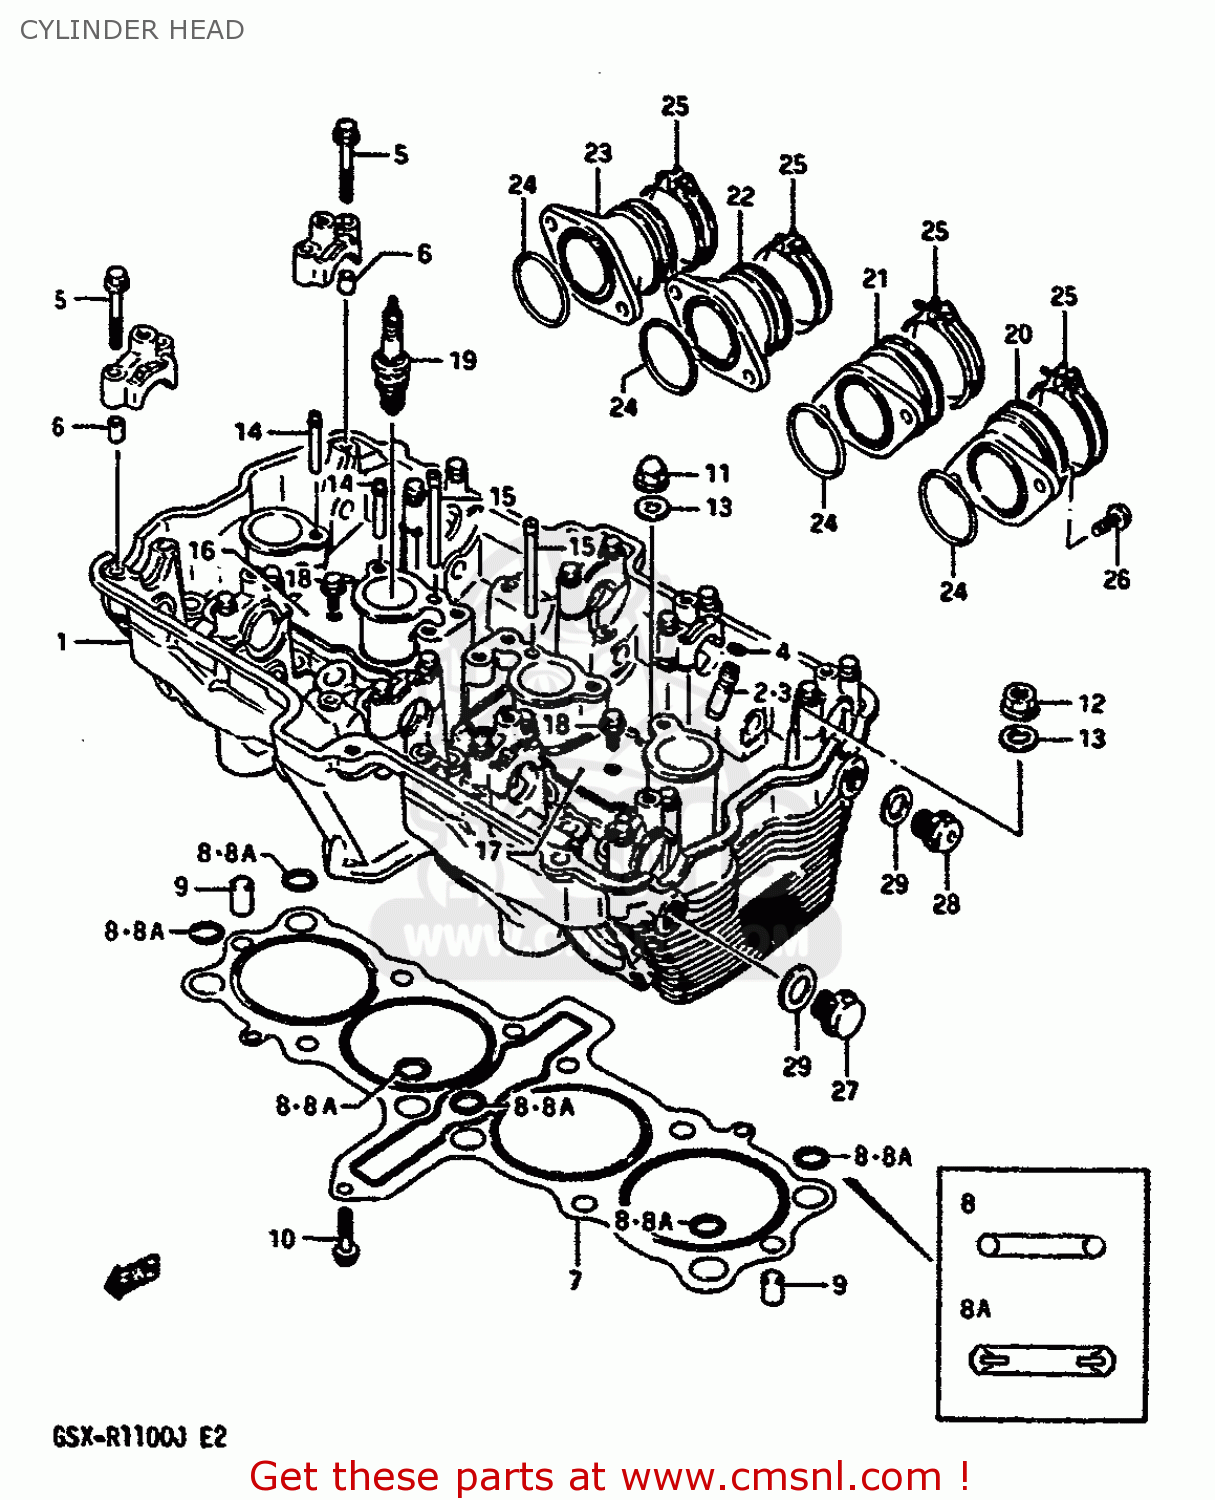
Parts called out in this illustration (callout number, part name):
1	HEAD ASSEMBLY,CYLINDER
2	GUIDE,VALVE
3	GUIDE,VALVE
4	RING,SNAP
5	BOLT(6X39)
6	PIN(6.2X8X11)
7	GASKET,CYLINDER HEAD (NAS)
8	O RING,HEAD GASKET
8A	O RING,HEAD GASKET
9	PIN
10	BOLT
11	NUT
12	NUT
13	GASKET(10.2X20X2).3 (NAS)
14	PIPE,OIL NO.1
15	PIPE,OIL NO.3
16	PLATE,OIL PIPE,R
17	PLATE,OIL PIPE,L
18	BOLT
19	SPARK PLUG
20	PIPE,INTAKE
21	PIPE,INTAKE
22	NET,INTAKE
23	PIPE,INTAKE
24	O RING(D:2.4,ID:39.7)
25	CLAMP
26	SCREW
27	PLUG
28	PLUG
29	GASKET(14X19.2X2) (NAS)
